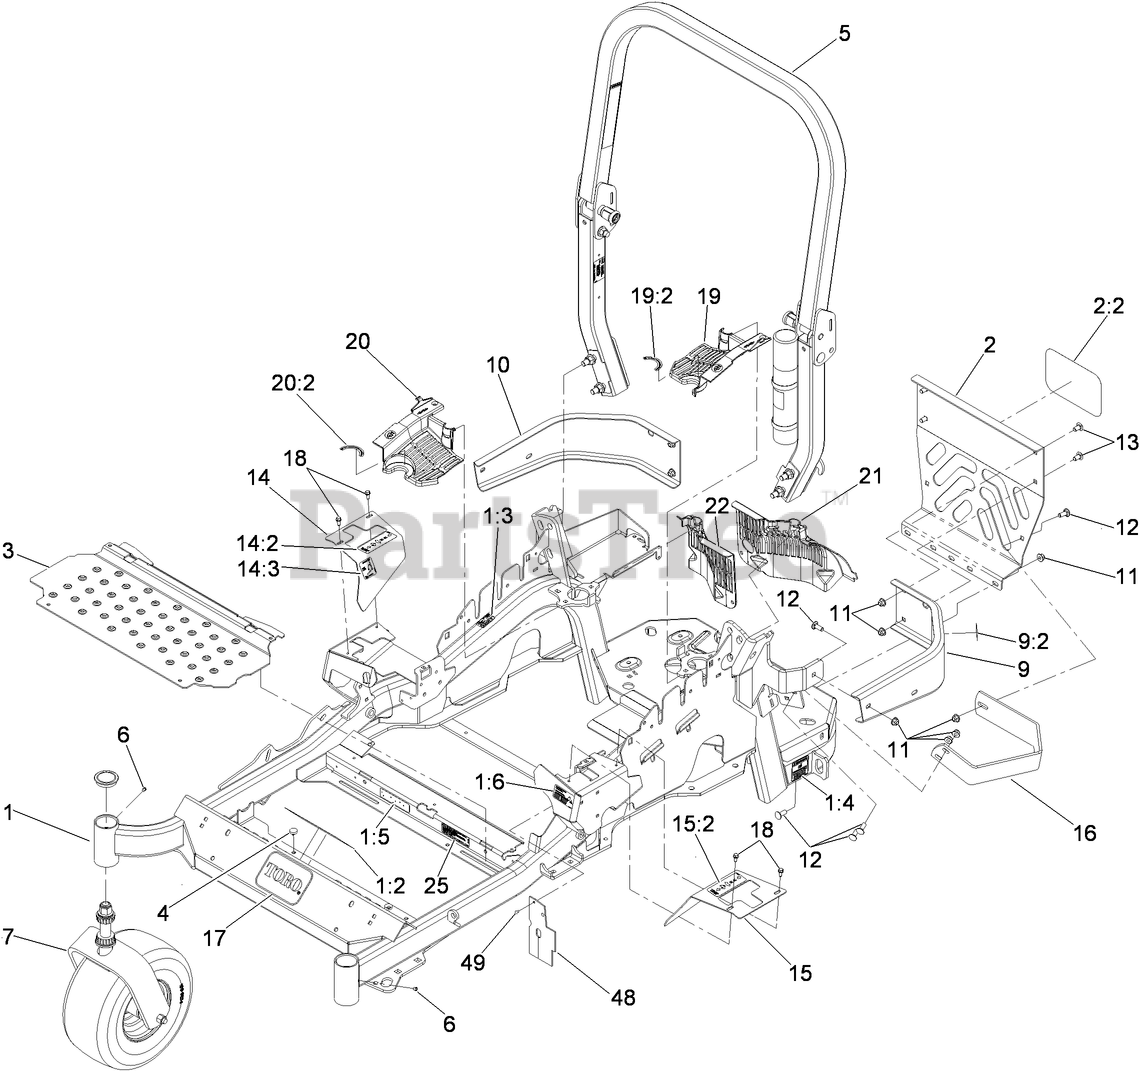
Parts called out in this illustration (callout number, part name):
1	MAIN FRAME ASM
1:2	DECAL-WARNING
1:3	DECAL-CAUTION
1:4	DECAL-BELT DRIVE
1:5	DECAL-ARRESTER, SPARK
1:6	DECAL-FUEL FILL
2	REAR GUARD ASM
2:2	DECAL
3	FLOORPAN
4	BUMPER
5	ROPS ASM
7	Caster Wheel ASM
9	LH BUMPER ASM
9:2	DECAL-CAUTION
10	BUMPER-RH
11	NUT-HF, NI
12	SCREW-CARR
13	SCREW-CARR
14	RH MOTION CONTROL COVER ASM
14:2	DECAL-MOTION CONTROL
14:3	DECAL-PARK BRAKE
15	LH MOTION CONTROL COVER ASM
15:2	DECAL-MOTION CONTROL
16	GUARD-MUFFLER
17	DECAL
18	SCREW-HWH
19	LH HYDRO GUARD ASM
19:2	DECAL-HYDRO OIL
20	RH HYDRO GUARD ASM
20:2	DECAL-HYDRO OIL
21	GUARD-HYDRO, REAR (LH)
22	GUARD-HYDRO, REAR (RH)
25	DECAL-EMISSIONS
48	DEFLECTOR-AIR FLOW
49	RIVET-POP
